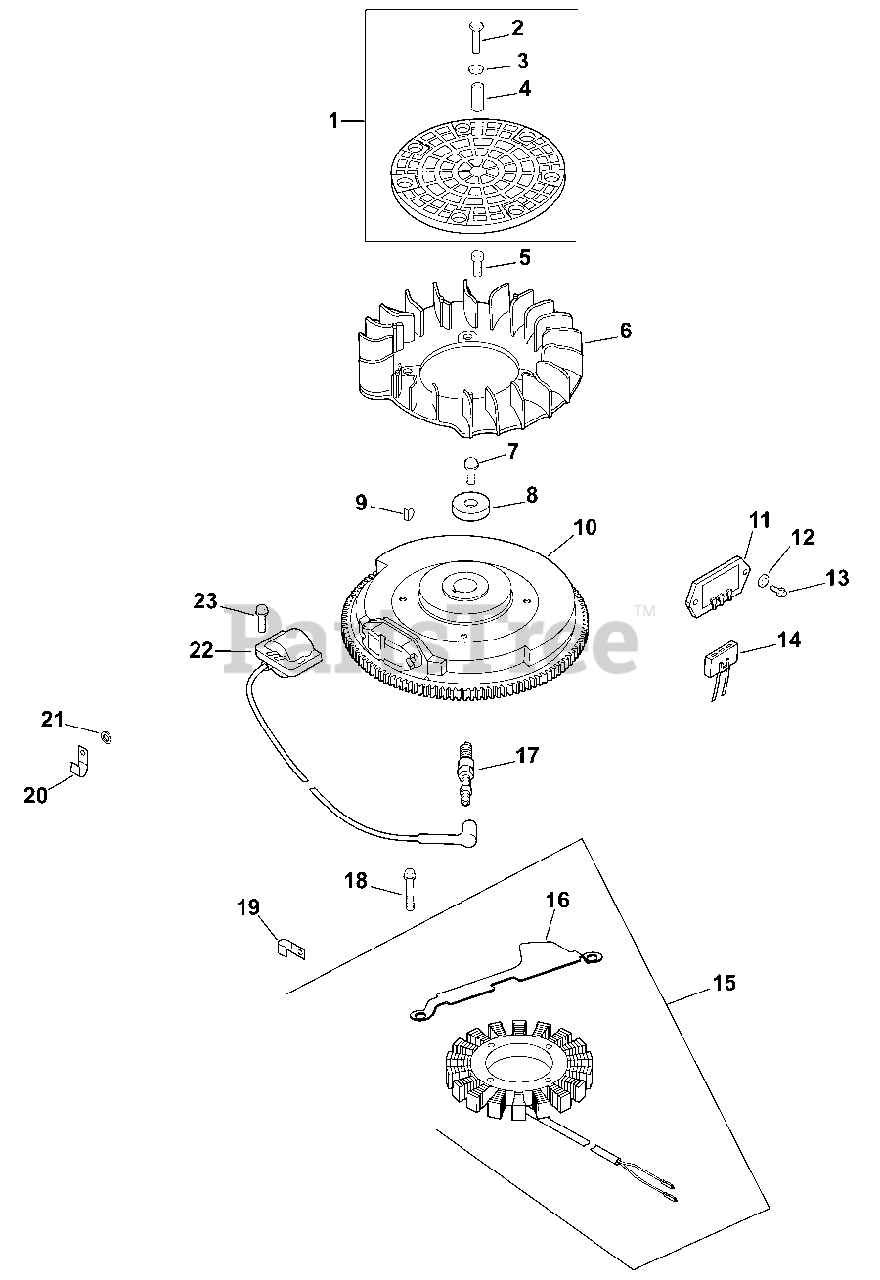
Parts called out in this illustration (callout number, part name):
1	KIT, GRASS SCREEN
2	SCREW, SLT HD CAP M4X0.7X25
3	WASHER, FLAT 3/16"
4	SPACER - DISCONTINUED
5	BOLT, SHOULDER
6	FAN (DOMED)-USE 24 157 17-S
7	SCREW, FLG M10X1.5X45 - (#25086361S)
8	WASHER, FLAT 13/32"
9	KEY, 3/16" X 5/8"
10	FLYWHEEL, PAINTED-USE 24 025 55-S
11	REG/RECT-15 AMP (KM)-USE 41 403 10-S
12	WASHER, FLAT 3/16"
13	SCREW, PHL HD #11-16X7/8"
14	CONNECTOR, BODY (KM)-USE 25 155 41-S
15	STATOR KIT - USE 237878-S
16	BRACKET, STATOR WIRE
17	PLUG, SPARK (STD)
18	SCREW, M5X0.8X25 - (#25086402S)
19	CLIP, CABLE
21	WASHER, FLAT 1/4" (O.D. 1/2")
22	MODULE, IGNITION-USE 24 584 45-S
23	SCREW, FLG THD FRM M5X.8X20-(#25086399S)
